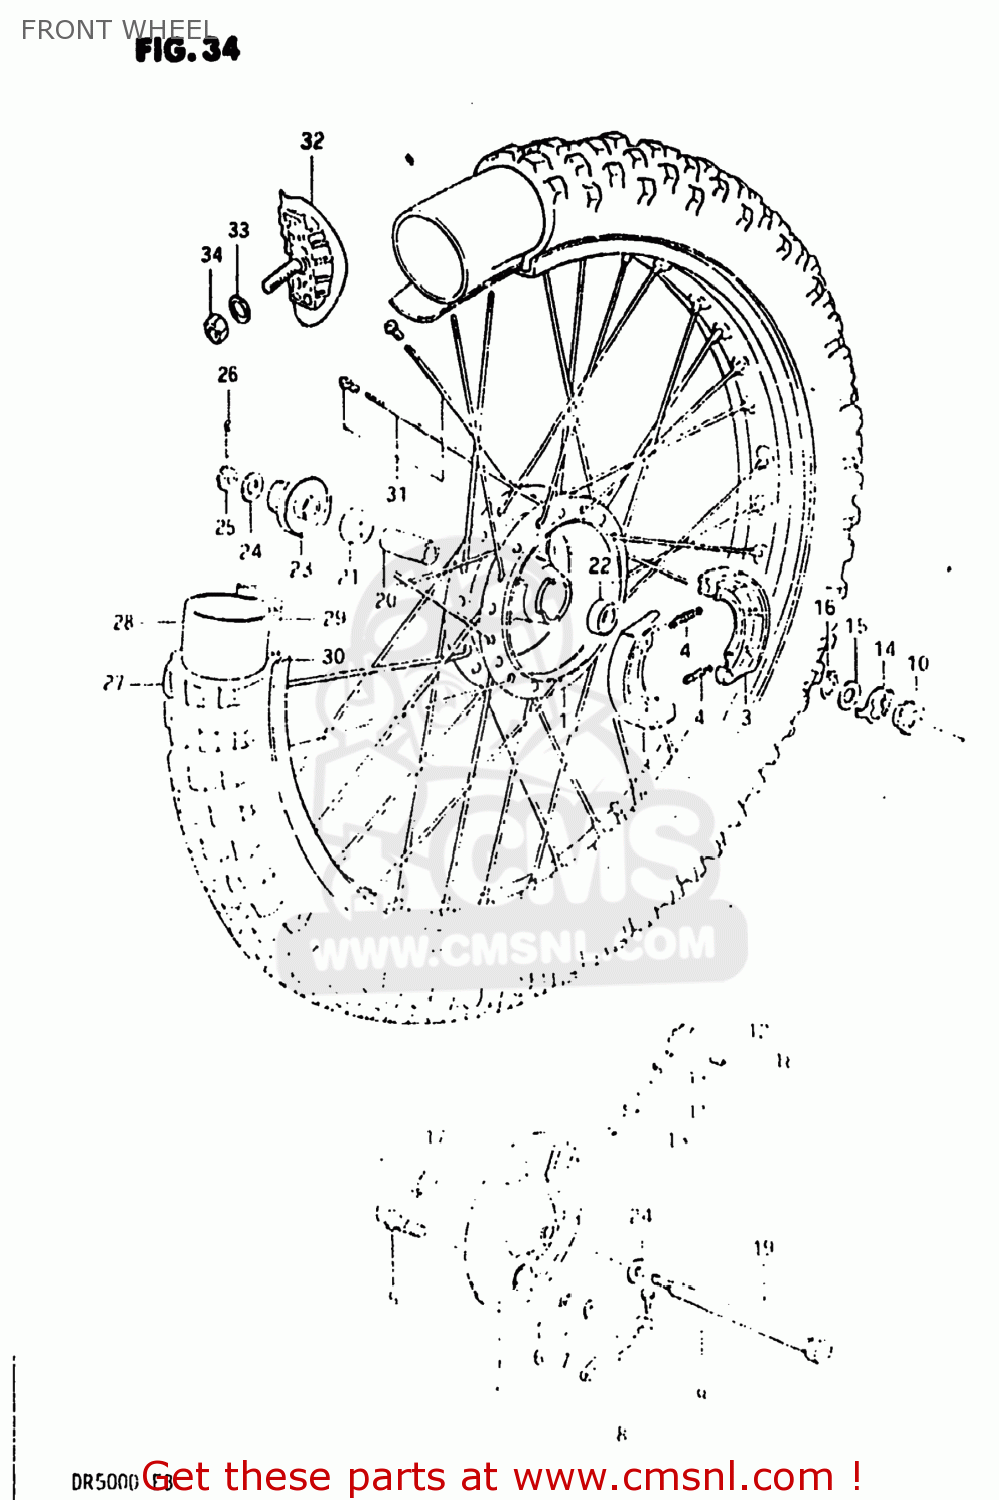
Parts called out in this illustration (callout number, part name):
1	HUB,FRONT
2	PANEL,FRONT HUB
3	SHOE,BRAKE (MCA)
4	SPRING(L:34)
5	CAM,FRONT BRAKE
6	O-RING (D:2.4 ID:13.8)
7	WASHER (14.5X22X1.6)
8	LEVER,FRONT BRAKE CAM
9	BOLT
10	GEAR,SPEEDOMETER
11	PINION,SPEEDOMETER
12	BUSH,METER GEAR OUTER
13	WASHER (5.1X9X0.4)
14	DRIVER,SPEEDOMETER GEAR
15	WASHER(18.5X24X1)
16	CIRCLIP
17	OIL SEAL (43X58X7)
18	SCREW
19	AXLE,FRONT
20	SPACER (12.6X19X52)
21	BEARING, RH
22	BEARING
23	SPACER,FRONT AXLE,RIGHT
24	WASHER
25	NUT, REAR AXLE
26	COTTER PIN
27	TIRE,FRONT
28	TUBE,INNER
29	PROTECTOR,WHEEL,INNER
30	RIM,FRONT WHEEL
31	SPOKE SET,FRONT
32	STOPPER,BEAD
33	WASHER
34	NUT
